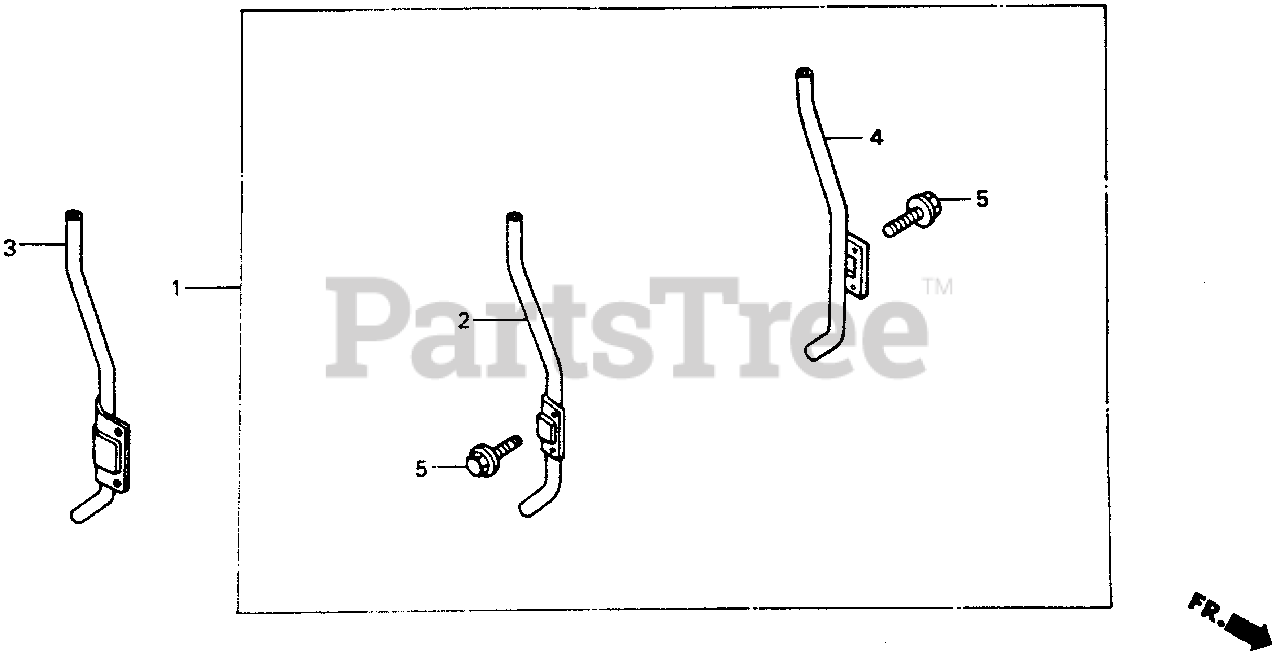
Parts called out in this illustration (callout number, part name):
1	STAND KIT, SUPPORT
2	POST, R. SUPPORT
3	POST, R. SUPPORT
4	POST, L. SUPPORT
5	BOLT, FLANGE (8X20)
